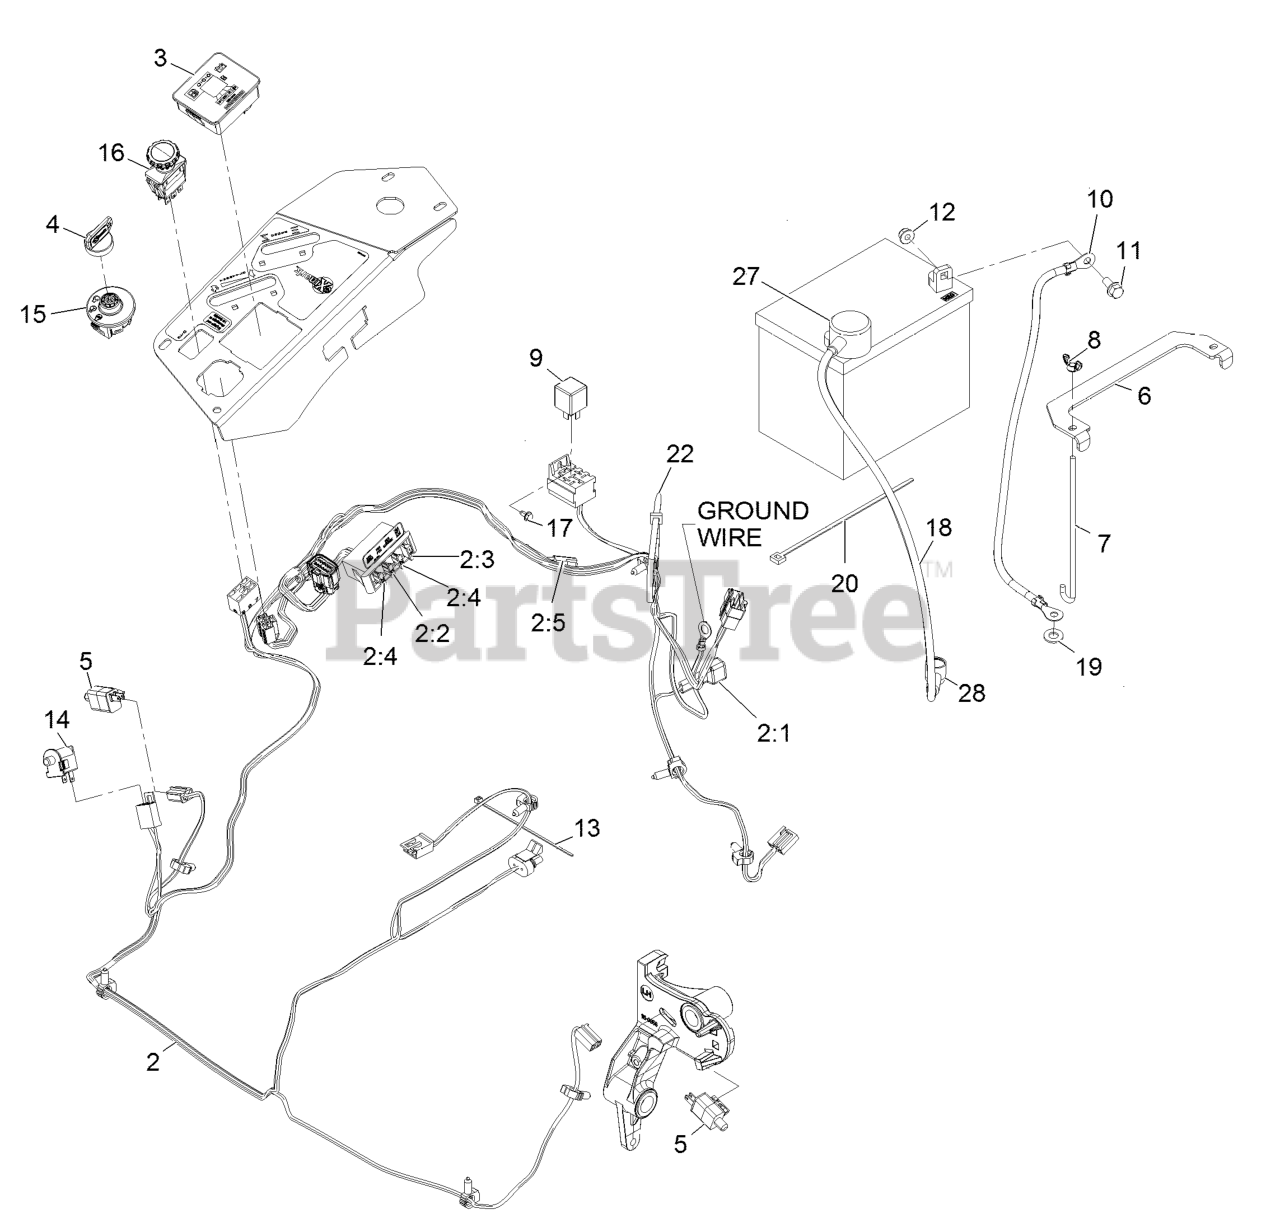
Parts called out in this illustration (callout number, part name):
2	HARNESS-WIRE, MAIN
2:2	FUSE-BLADE, 10 AMP
2:3	FUSE-BLADE, 15 AMP
2:4	FUSE-BLADE, 25 AMP
2:5	CAP-PLUG
3	FUEL/HOUR METER ASM
4	KEYS-IGNITION (SPARE PAIR
4	KEY-IGNITION
6	STRAP-TIE DOWN, BATTERY
7	BOLT-HOLDDOWN
8	WINGNUT
10	CABLE-BATTERY, NEGATIVE
11	SCREW-HHF
12	NUT-HF, NI
13	TIE-CABLE
14	SWITCH-BAIL
16	SWITCH-PTO, 10 AMP
17	SCREW-HWH
18	CABLE-BATTERY, POSITIVE
19	WASHER-FLAT
20	TIE-PLASTIC
22	TIE-PLASTIC
27	INSULATOR-BATTERY
28	INSULATOR-SOLENOID
